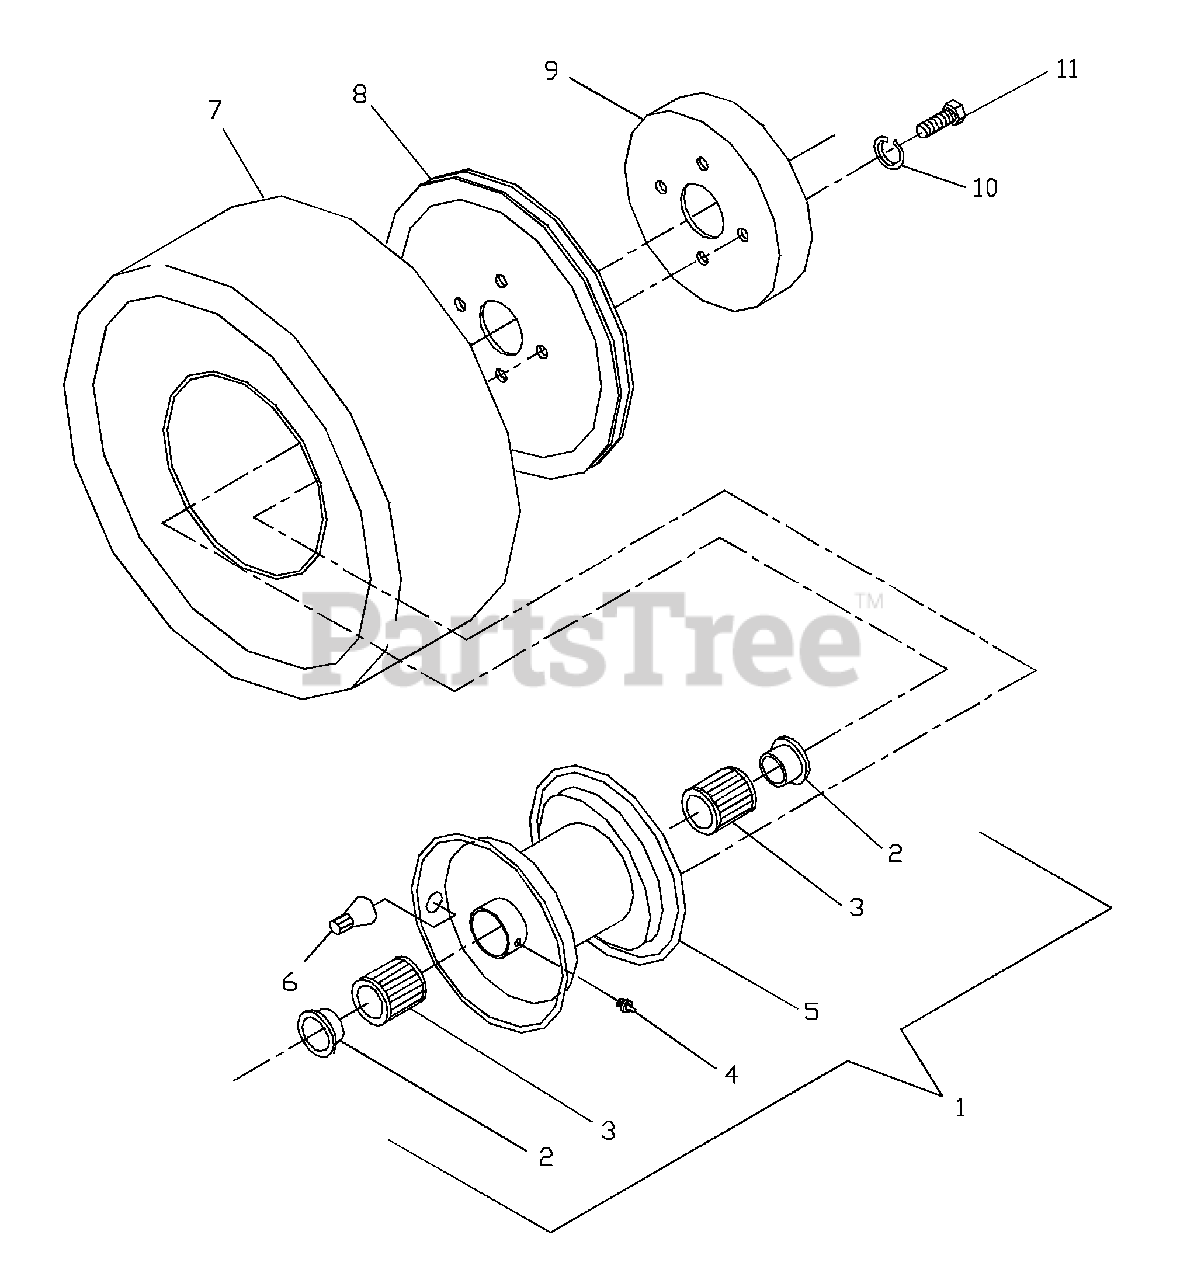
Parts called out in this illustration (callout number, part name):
1	WHEEL ASM.
3	ROLLER BEARING
4	ZERK 1/4-28 STRHT
5	RIM
8	TRACTION PULLEY
9	BRAKE DRUM
10	SLW 3/8 STD
11	HCS 3/8F X 3/4
